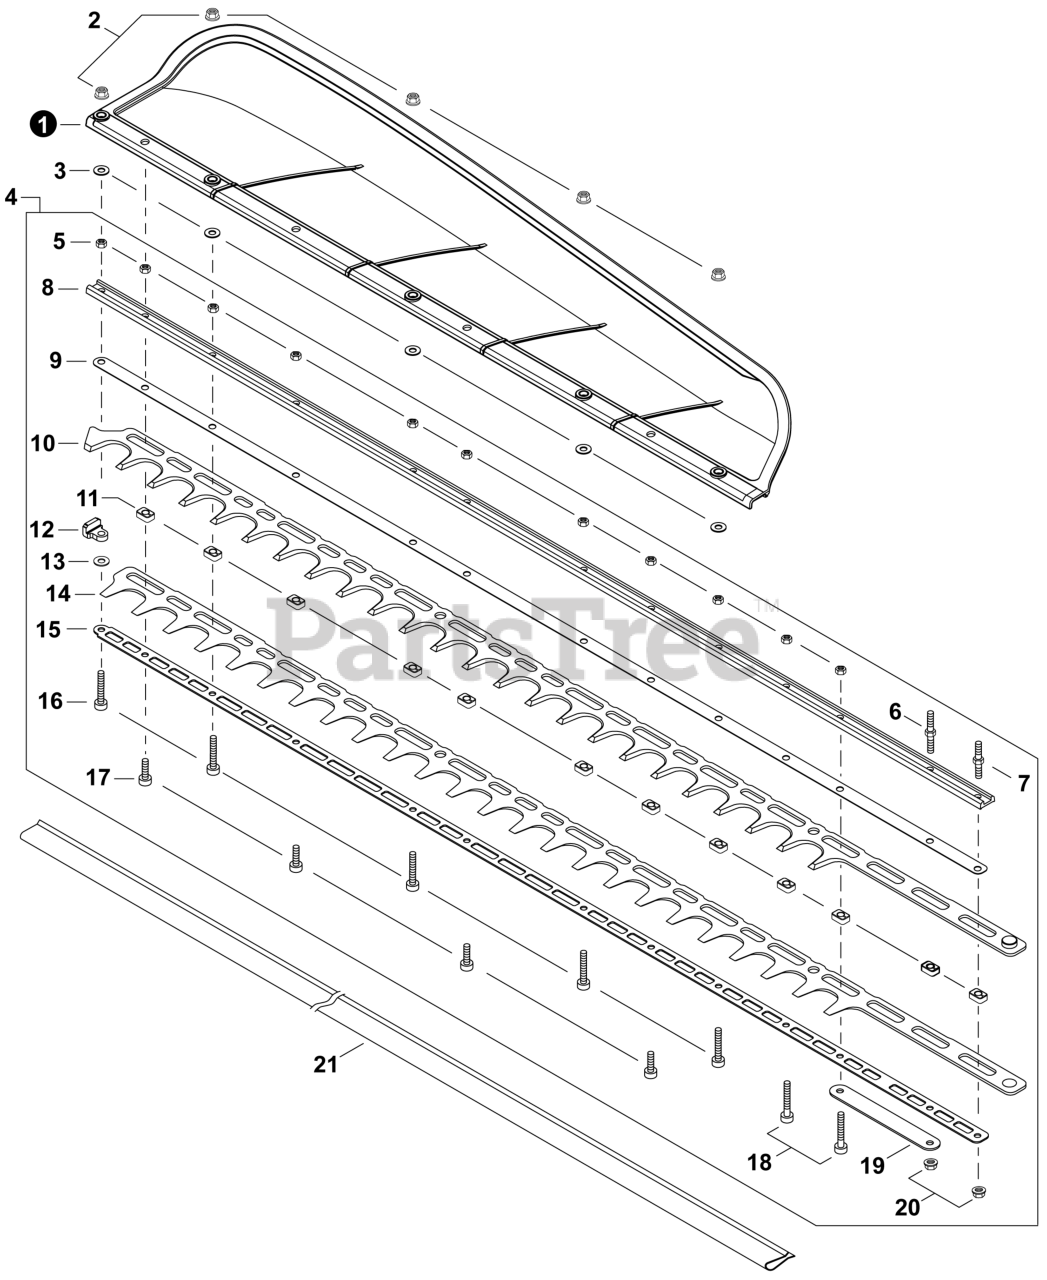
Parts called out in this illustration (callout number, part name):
1	DEFLECTOR, DEBRIS
2	NUT, FLANGE M5
3	WASHER, FLAT 5.5x10x0.8
4	CUTTER ASSY, 37.6"
6	STUD, MOUNTING M5x44
7	STUD, MOUNTING M5x36
8	SUPPORT, BLADE 37.6"
9	SUPPORT, BLADE 37.6"
10	BLADE - UPPER - 37.6"
14	BLADE - LOWER - 37.6"
15	SUPPORT, BLADE 37.6"
16	BOLT, TORX 5x25
17	BOLT, TORX 5x16
18	BOLT, TORX 5x30
19	PLATE, EYE
20	NUT, FLANGE M5
21	SCABBARD
